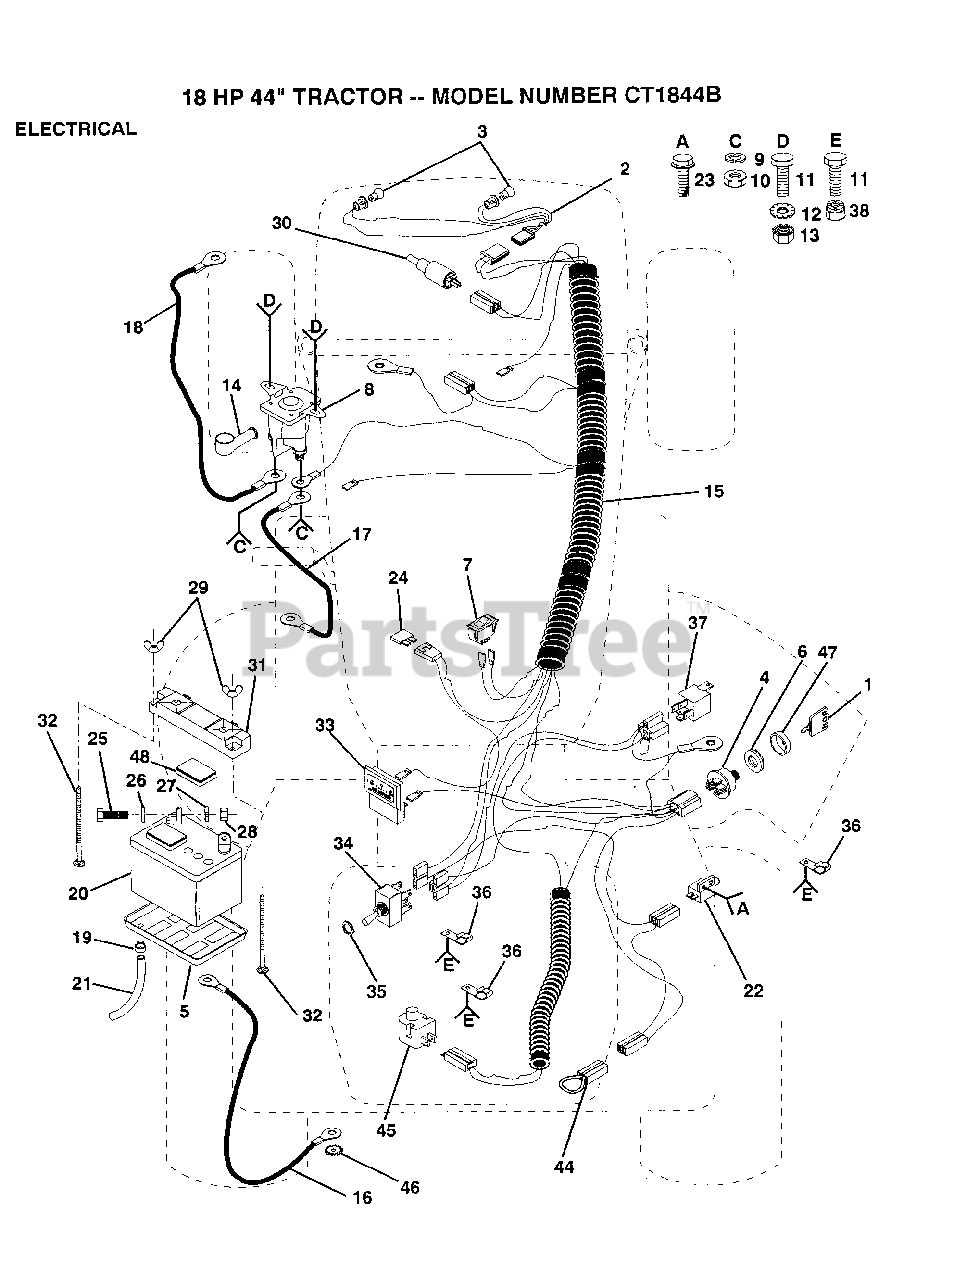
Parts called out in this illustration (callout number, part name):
1	KEY
2	HARNESS T
5	"TRAY T, BATTERY"
6	NUT IGNITION
7	SWITCH LT
10	NUT
11	BOLT
13	NUT
16	"CABLE T, BATTERY"
17	CABLE LT
18	CABLE T
19	HOSE CLAMP T
22	SWITCH-INTER. GT
23	SCREW
24	FUSE HYT
25	BOLT LT
26	WASHER
27	LOCKWASHER
32	BOLT
33	AMMETER
34	"SWITCH,PTO"
35	HEX NUT T
36	CLIPT
37	RELAY ASSY T
45	SWITCH SEAT
46	LOCKWASHER
48	"CAP,BATTERY "
